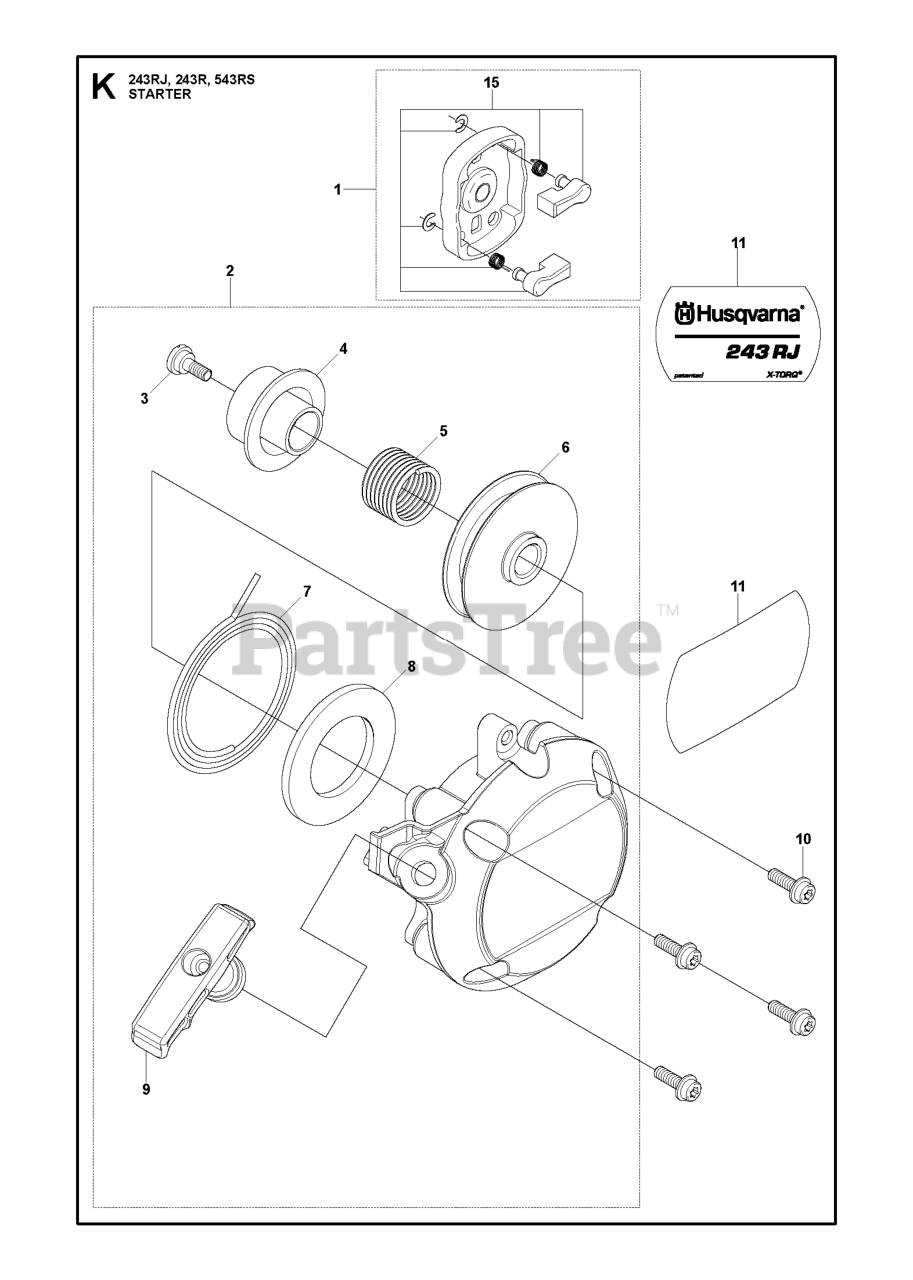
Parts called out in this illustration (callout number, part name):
4	PLATE, CAM
5	SPRING, DAMPER
11	LABEL,RECOIL
